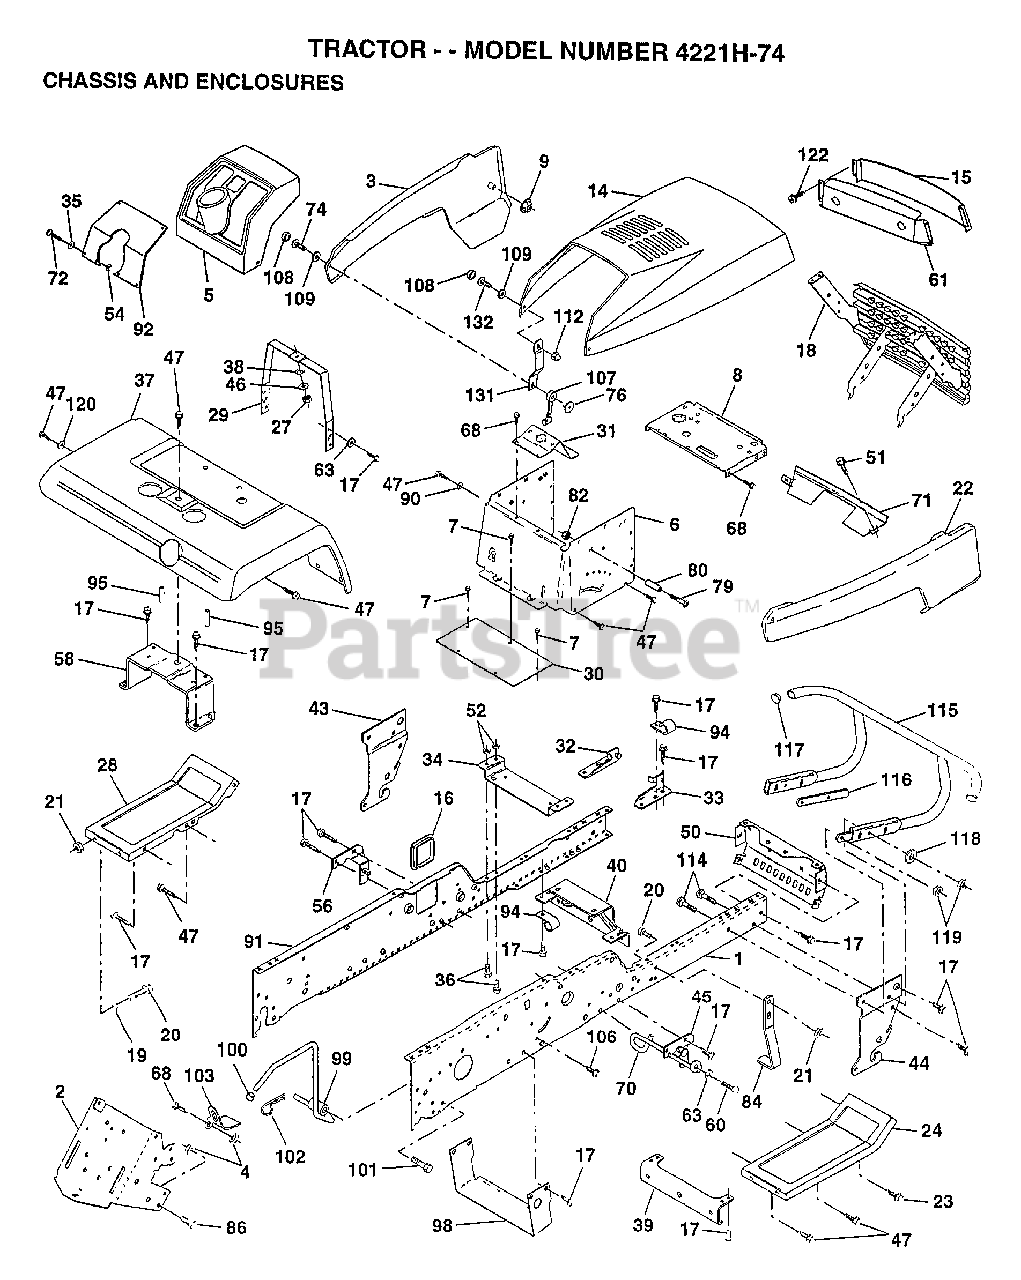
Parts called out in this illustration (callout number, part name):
1	"RAIL,FRAME RH"
2	DRAWBAR GT
3	PANEL ASM SIDE LH
4	NUT.7/16
5	DASHBOARD BLACK
6	DASH LOWER
7	SCREW
8	SUPPORT.DASH.BTRY
9	PAL NUT LT
15	LENS.BAR.CLEAR
16	COVER ACCESS
17	SCREW
19	WASHER
20	BOLT
22	PANEL ASM SIDE RH
23	SCREW GTV
24	FOOTREST.RH.LT/GT
28	FOOTREST.LH.LT/GT
29	SADDLE.HYDRO.95
30	SADDLE.HYDRO.95
31	BRAKET.SUPT.STEER
32	BRACKET ASM FRAME
33	BRACKET ASM FRAME
34	BRACKET.ENG.SUPT.
35	WASHER
36	BOLT
38	LOCKWASHER
39	BRACKET.AXLE.FRT.
40	"BRKT SUPPORT,AXLE"
43	BRACKET.SUS.FT.LH
44	BRACKET.SUS.FT.RH
45	BRACKET ASM., SUSP CHASSIS RH
46	WASHER PM
47	SCREW LT
50	"BRKT CHASSIS,FRNT"
51	SCREW CRT
56	CONFLICT W/PART #
58	BRKT.ASM.FENDER
60	SCREW
61	BEZEL.ASM.
63	WASHER
68	SCREW LT
70	GUIDE.BELT.MID.SP
71	STRAP.GRILLE.424
72	SCREW
74	SCREW
76	WELDNUT
79	SCREW
80	SPACER LT
84	STOP.OVER.CENTER
86	BOLT
90	LOCKWASHER
91	"RAIL FRAME,LH"
92	"PLATE-DASH,SLKSCR"
94	CLIP GTV
95	NUT-PUSH YT
98	BRACKET SKID CHAS
99	ROD BYPASS
101	SCREW LT
102	RETAINER M
103	LOCK BYPASS BRKT
107	HOOD LATCH T
108	SNAP CAP LT
109	WASHER LT
112	ACORN NUT RB
114	BOLT.3/8-14X1.25
115	BUMPER.ASM
116	BRACKET.EXT.BUMP.
117	PLUG.PLASTIC
118	WASHER
120	WASHER
131	BKT.SPT.HOOD/PANL
132	SCREW.10-24X3/8.
